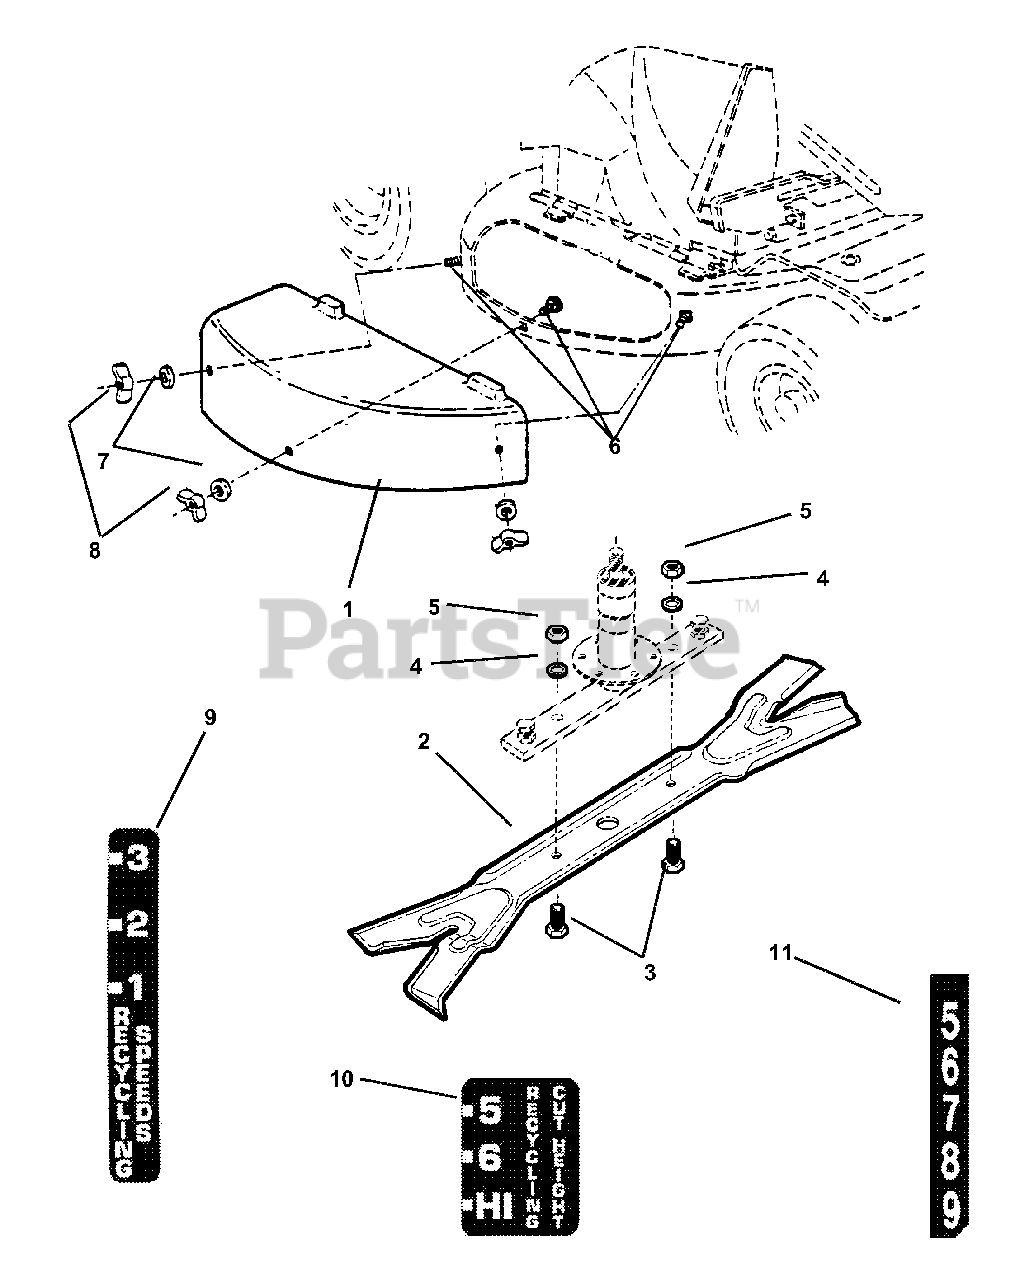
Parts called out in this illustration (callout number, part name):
1	COVER, Side Chute
2	BLADE, 33" Ninja
3	SCREW, Hex Head, 1/2-20 x 1
4	WASHER, 1/2
5	NUT, Hex Jam, 1/2-20
6	BOLT, Carriage, 5/16-18 x 3/4
7	WASHER, Flat, 5/16
8	NUT, Wing, 5/16-18
9	DECAL, Speed
10	DECAL, Height of Cut
11	DECAL, Cut Height
